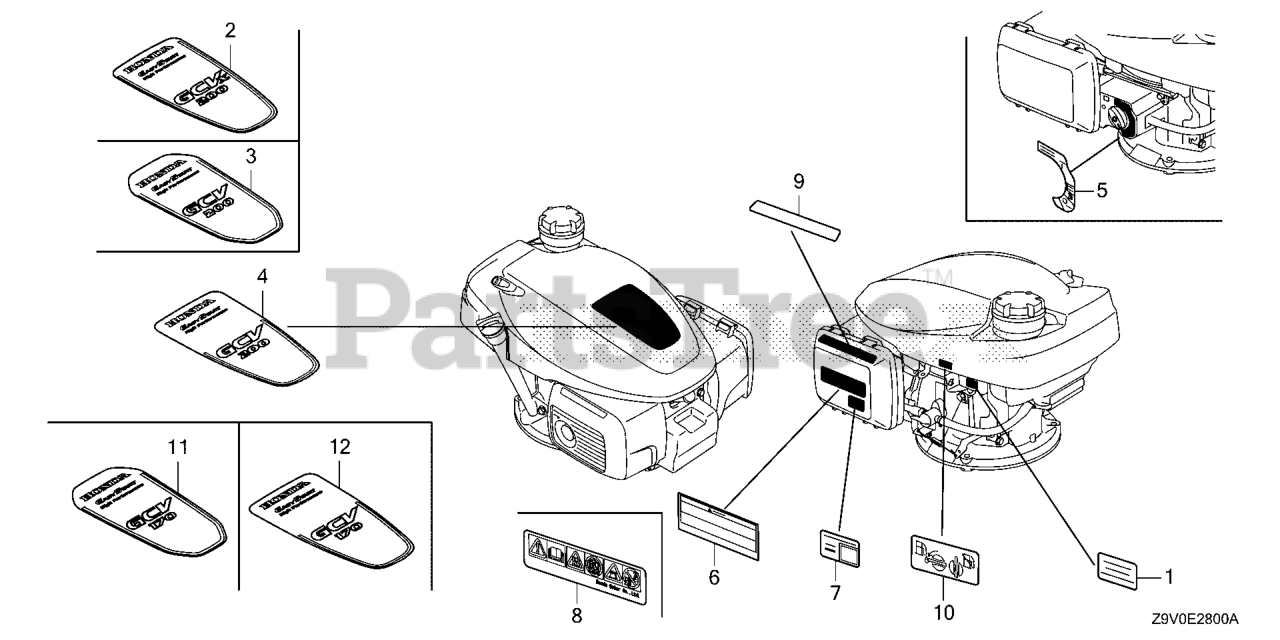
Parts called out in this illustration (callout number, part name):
1	LABEL, WARNING (NOT CERTIFIED FOR SALE)
3	MARK, TOP COVER
5	MARK, ENGINE SWITCH
6	MARK, OPERATOR CAUTION
